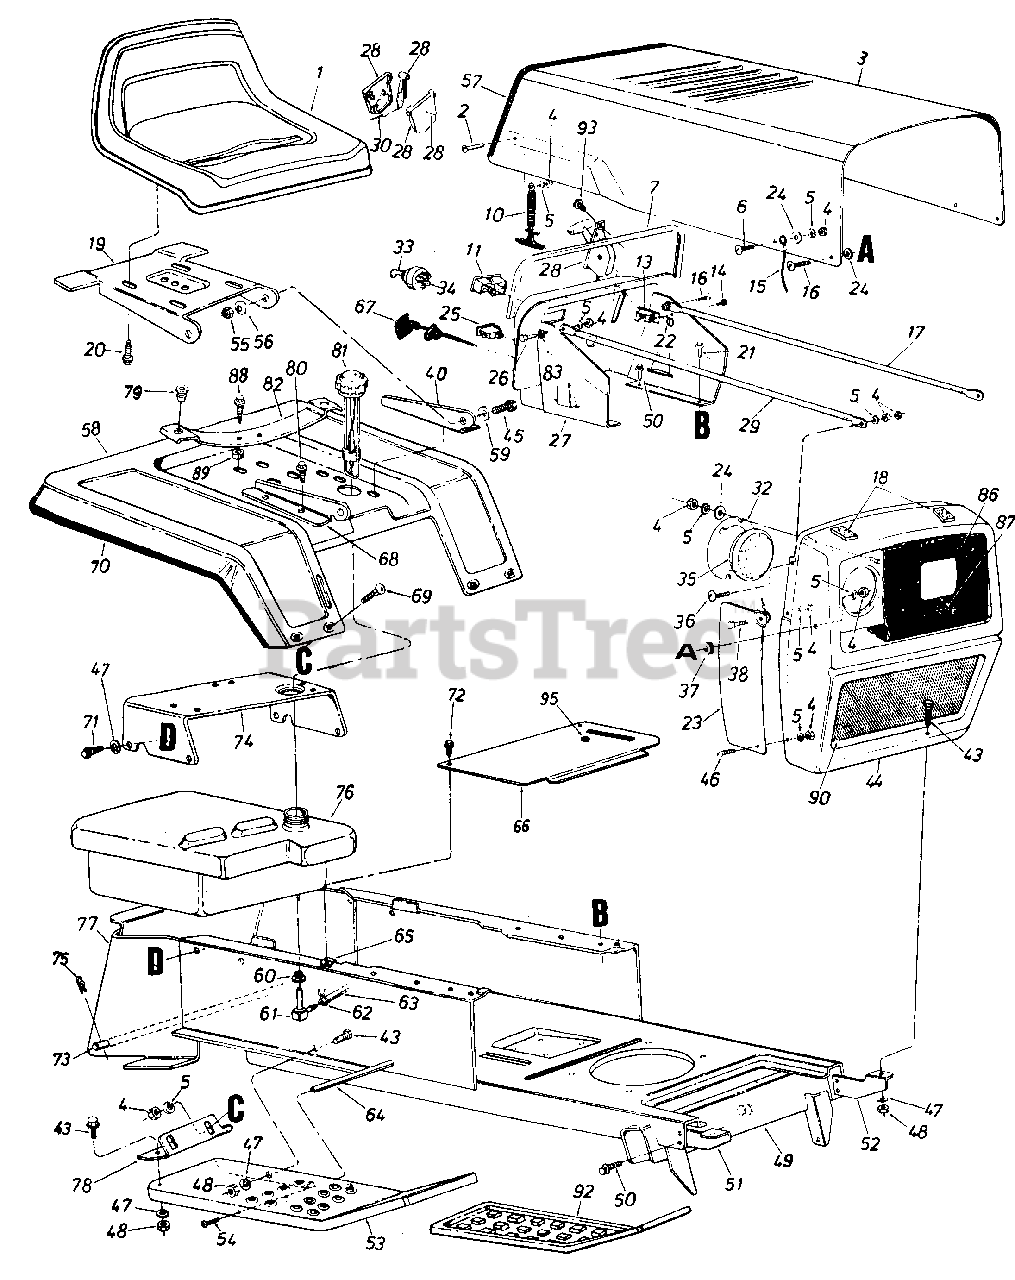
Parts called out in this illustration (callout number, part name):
1	Seat Assembly
2	Truss Mach. Scr. 1/4-20 x .50" Lg.*
5	L-Wash. 1/4" Scr.*
6	Truss Mach. Scr. 1/4-20 x .50" Lg.*
7	Vinyl Molding Strip-29"
10	Hood Latch Ass'y.
11	Ammeter
13	Circuit Breaker 8 Amp.
14	Hex Tap Scr. #10 x .50" Lg.*
15	Hood Stop
16	Truss Mach. Scr. 1/4-20 x .75" Lg.*
17	Grille Positioning Rod
18	PVC Foam Strip 1/2 x 1.00" x 2.00" Lg.
19	Seat Pivot Brkt.
20	Hex Wash. Hd. AB-Tap Scr. 318 x .75" Lg.
21	Hex Thd. Rolling Scr. 1/4" x .50" Lg.
22	Speed Nut #10Z
23	Grille Side Panel-R.H.
24	Fl-Wash. 1/4" I.D.
25	Light Switch
26	Truss Hd. Scr. 1/4-20 x 1.00" Lg. *
27	Dash Panel Ass'y.
28	Throttle Control Box Comp.
29	Grille Positioning Rod
30	Throttle Control Cable
32	Head Lamp Retainer
33	Ignition Key
34	Ignition Switch
35	Head Lamp
36	Truss Machine Scr. 1/4-20 x .75" Lg.*
37	Rubber Wash. .50" I.D. x 1.00 O.D. x .25 Thk.
38	Truss Mach. Scr. 1/4-20 x .50" Lg.*
40	Seat Bracket-L.H.
43	Hex Scr. 5/16-18 x .75" Lg.*
44	Grille Ass'y.
45	Hex Bolt 5/16-18 x .75" Lg.*
46	Truss Mach. Scr. 1/4-20 x .50" Lg.*
47	L-Wash. 5116" I.D.*
48	Hex Nut 5/16-18 Thd.*
49	Lower Frame Ass'y.
50	Hex Thd. Rolling Scr. 5116" x.75" Lg.
51	Grille Mount Brkt.-R.H.
52	Grille Mount Brkt.-L.H.
53	Running Board-R.H.
54	Truss Mach. Scr. 5/16-18 x .75" Lg.
55	Hex Cent. L-Nut 5/16-18 Thd.
56	Bell-Wash. .34" I.D. x .88 O.D.
57	Vinyl Moulding Strip-30"
60	Bushing
61	90ø Nipple
62	Hose Clamp 3/8"
63	Gas Line 46" Lg.
64	Running Board Rod
65	Speed Nut #10-24
66	Transmission Cover Ass'y.
67	Choke Control Comp.
68	Seat Bracket-R.H.
69	Carr. Bolt 1/4-20 x .50" Lg.
70	Trim Strip-81" Lg.
71	Hex Thd. Rolling Scr. 5/16-24 x .75" Lg.
72	Truss Hd. Scr. #10 x .50" Lg.
73	Hitch Rod
74	Seat Mounting Channel
75	Internal Cotter Pin
76	Gas Tank
77	Hitch Plate
81	Gas Gauge
82	Seat Spring
83	External Wash. 1/4" I.D.
86	Headlight Bezel
87	Hex Wash. Hd. F-Tap Scr. #8-32 x .38" Lg.
88	Hex Self-Tap Scr. 5/16-18 x 1.25" Lg.
89	Spacer
90	Grille Screen
92	Foot Pad
93	Truss Mach. AB-Tap Scr. #10 x .50" Lg.
95	Snap Bushing
